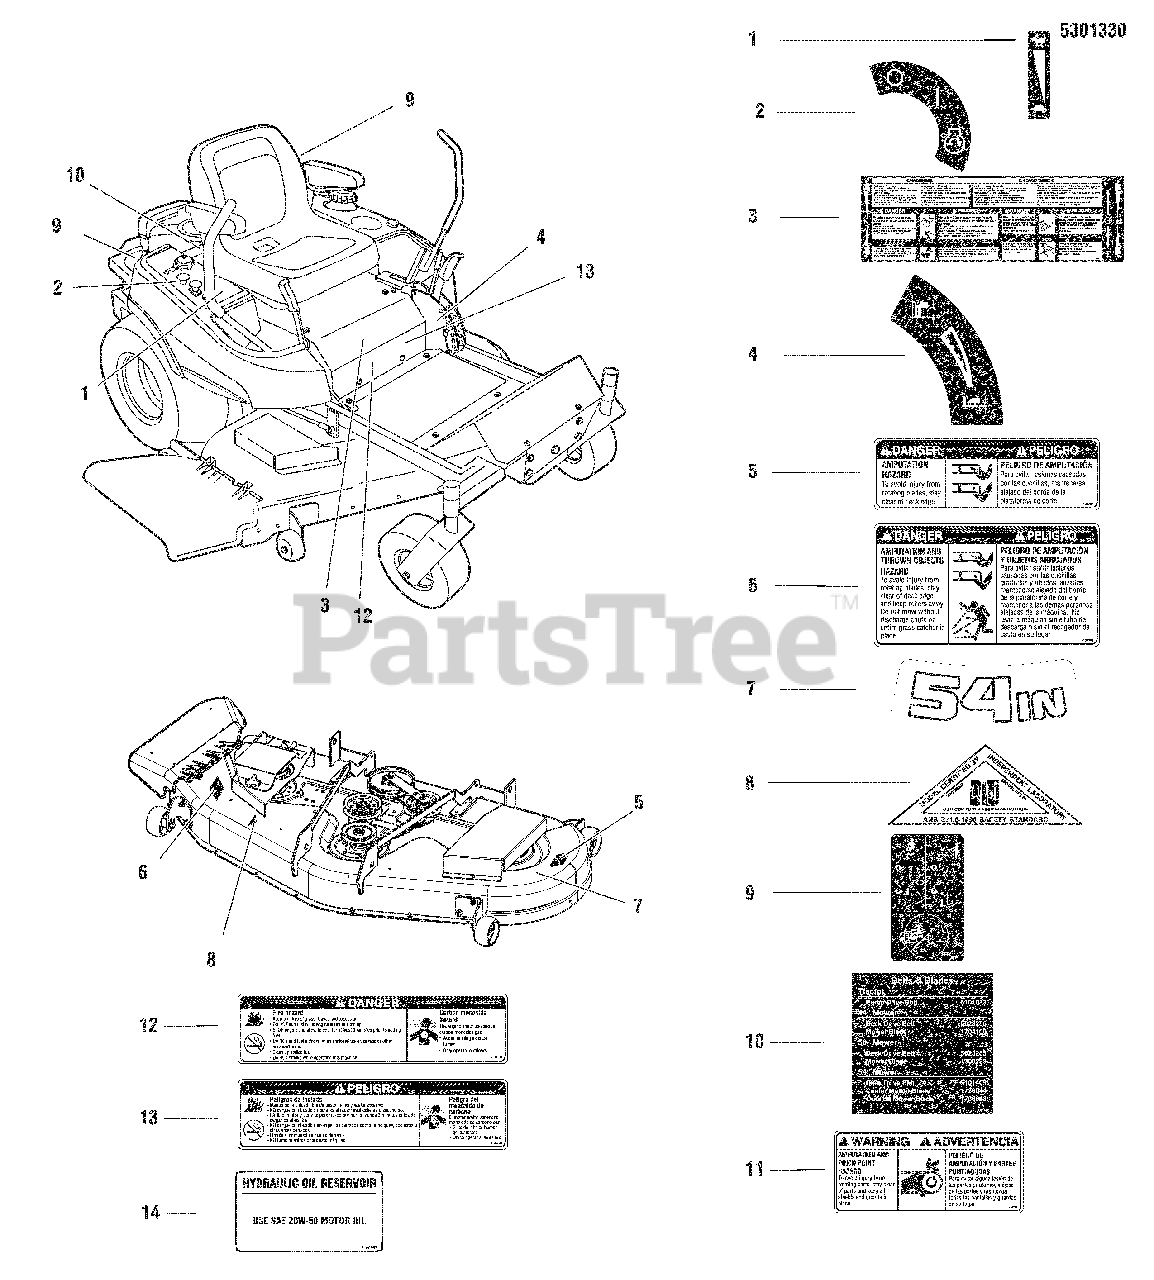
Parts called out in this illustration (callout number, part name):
1	DECAL, THROTTLE CONTROL
2	DECAL, IGNITION SWITCH
3	DECAL, MAIN, SNAPPER 355Z2654
4	DECAL, HEIGHT OF CUT
5	DECAL, DANGER, MOWER
6	DECAL, DANGER, MOWER DISCHARGE,8.75X2.13
7	DECAL, 54"
8	DECAL, OPEI WALK/RIDE
9	DECAL, TRANSAXLE RELEASE
10	DECAL, BELT & BLADE SNAPPER
11	DECAL, WARNING, HAND IN PULLEY
12	DECAL, DANGER, FIRE
13	DECAL, DANGER, FIRE (SP)
14	DECAL, HYDRAULIC OIL, SAE 20W50
